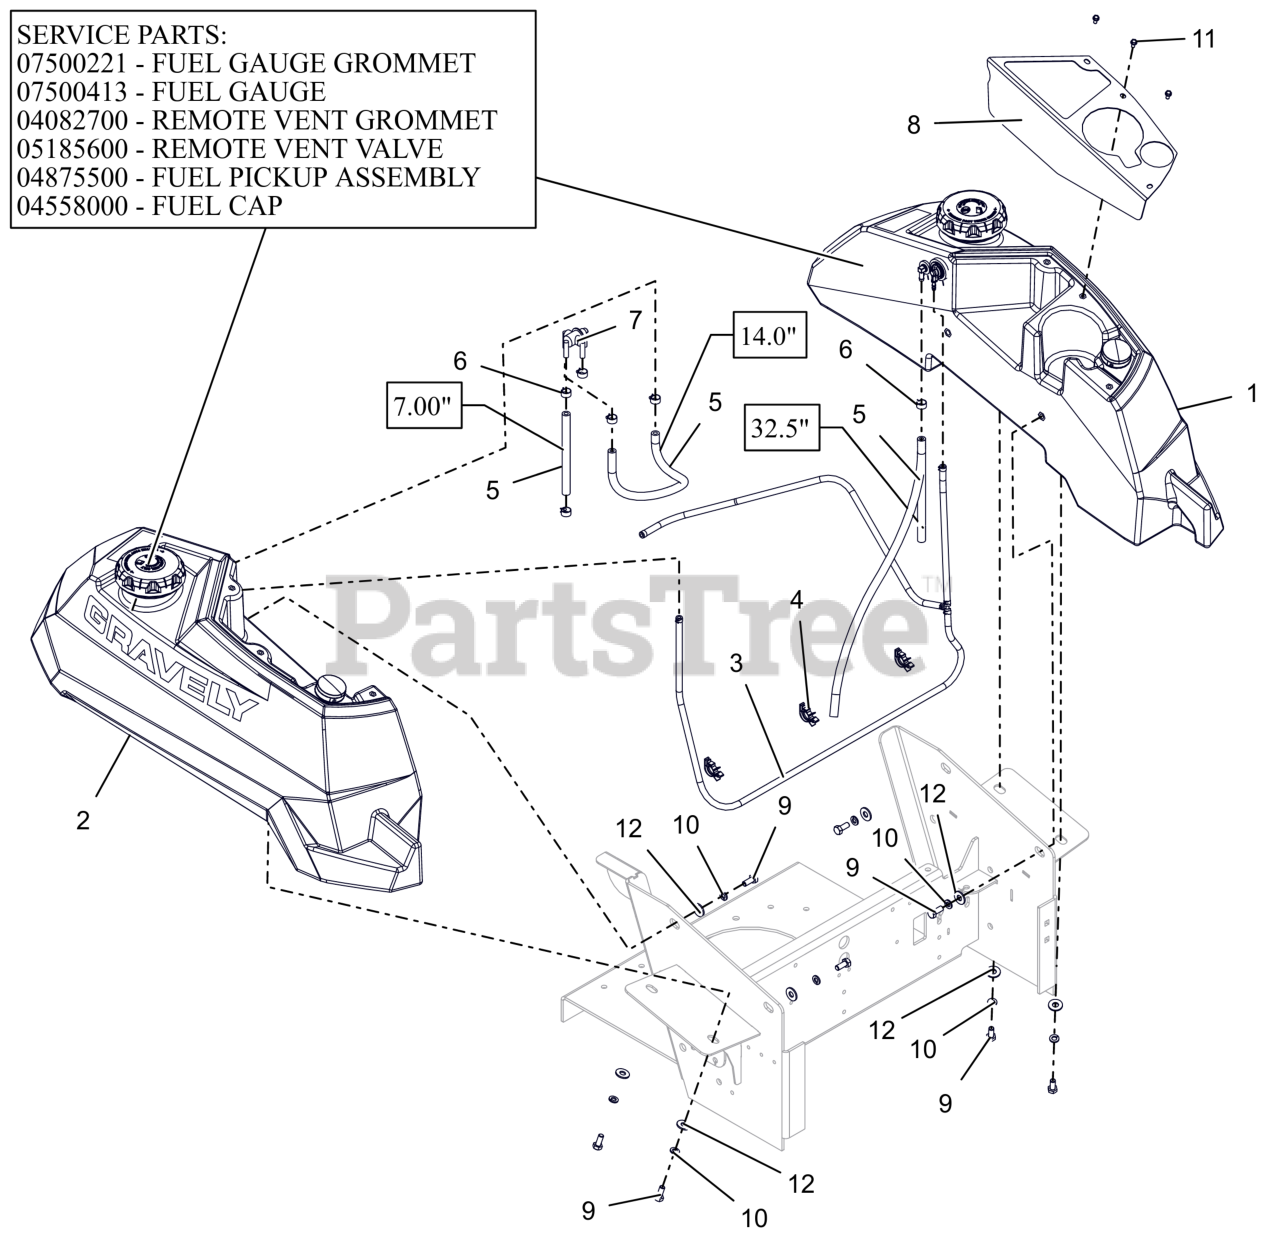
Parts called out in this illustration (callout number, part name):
1	ASM, LH - PT100 FUEL TANK
1	GROMMET, FUEL GAUGE
1	GAUGE, REMOTE SEALED FUEL
1	GROMMET, REMOTE VENT NITRILE
1	VALVE, COMBINATION VENT 3/16
1	ASSM,LRG TANK FUEL PICKUP LINE
1	CAP, FUEL VENTIN AUTOLOCK
2	ASM, RH - PT100 FUEL TANK
2	GROMMET, FUEL GAUGE
2	GAUGE, REMOTE SEALED FUEL
2	GROMMET, REMOTE VENT NITRILE
2	VALVE, COMBINATION VENT 3/16
2	ASSM,LRG TANK FUEL PICKUP LINE
2	CAP, FUEL VENTIN AUTOLOCK
3	ASM, VAPOR LINE
4	WIRE CLIP
5	HOSE, .25 LOW-PERM BULK GAS
6	CLAMP, FUEL LINE
7	VALVE, FUEL
8	PT100 CUPHOLDER PANEL - RED
9	BLT,HEX .31-18X.75 G5 ZCC
10	WSHR,LK-REG .312X.078 ZCC
11	SCR-MCH 10-24X.38 HWHSTAINLESS
12	WSHR,FLT .375X.875X.083 ZCC
